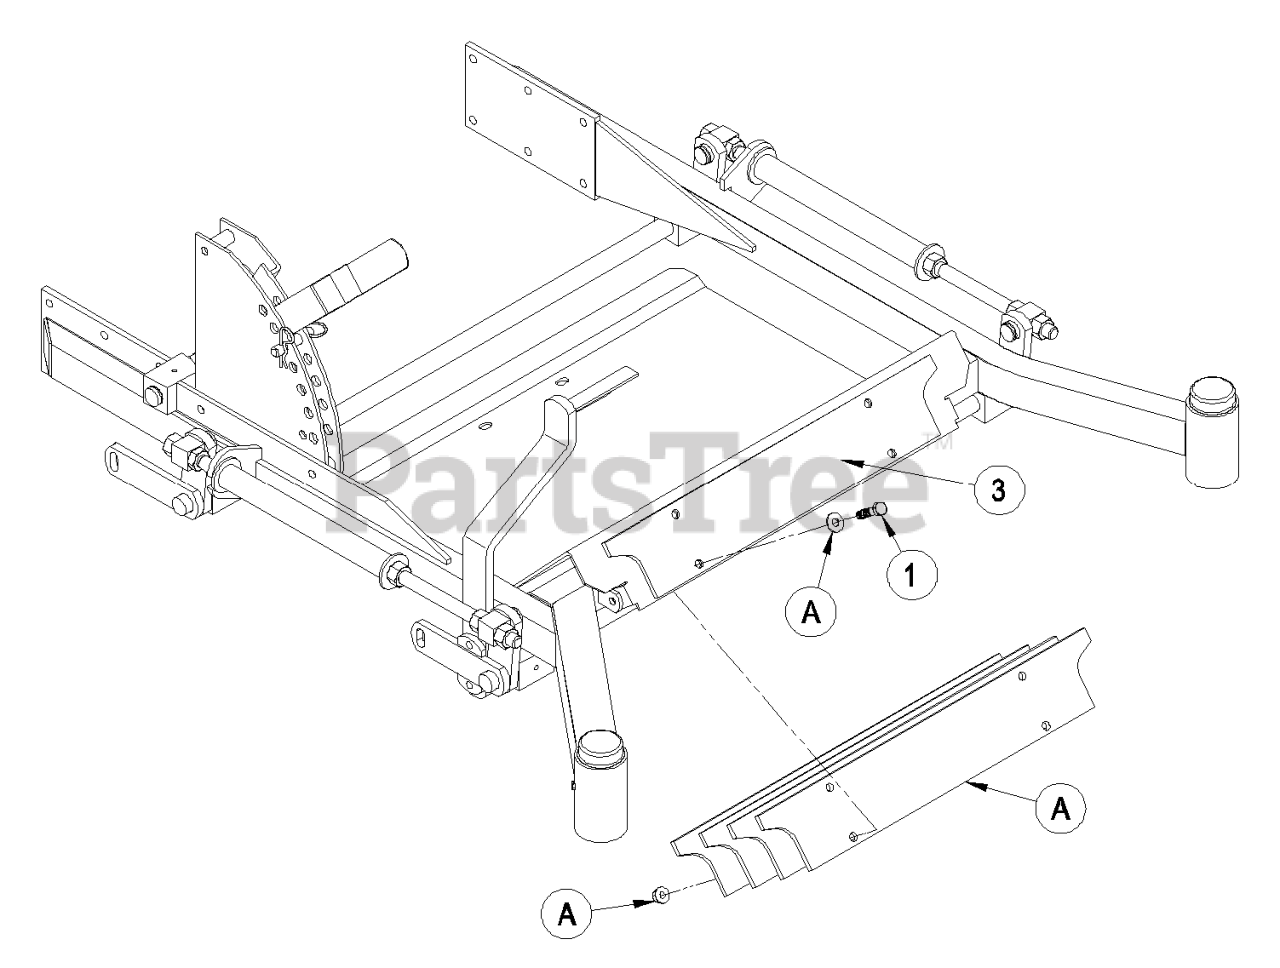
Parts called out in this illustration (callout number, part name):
1	SCREW-HH
3	PLATE, WEIGHT
A	WASHER-PLAIN
A	NUT-HF
